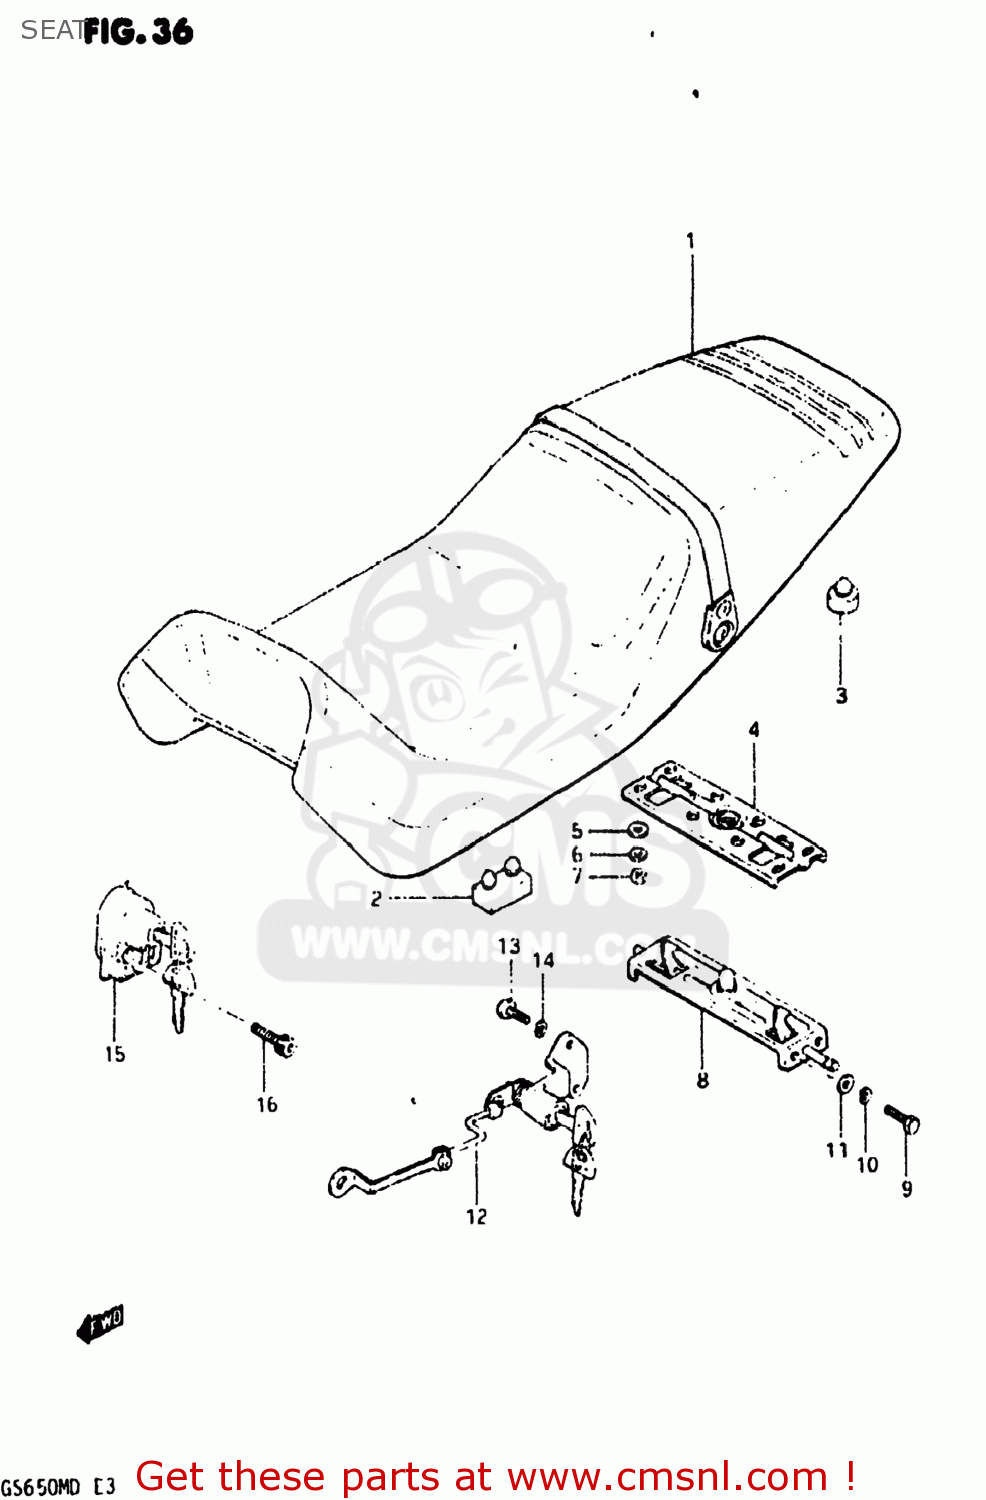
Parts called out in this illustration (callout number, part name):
1	SEAT ASSEMBLY
2	CUSHION
3	CUSHION
4	PLATE,SEAT LOCK GUIDE
5	WASHER
6	LOCK WASHER
7	NUT 6MM
8	PLATE,CLAMP GUIDE
9	BOLT
10	LOCK WASHER
11	WASHER
12	LOCK ASSEMBLY,SEAT
13	BOLT
14	LOCK WASHER
15	LOCK ASSY,HELMET
16	BOLT 5X25
